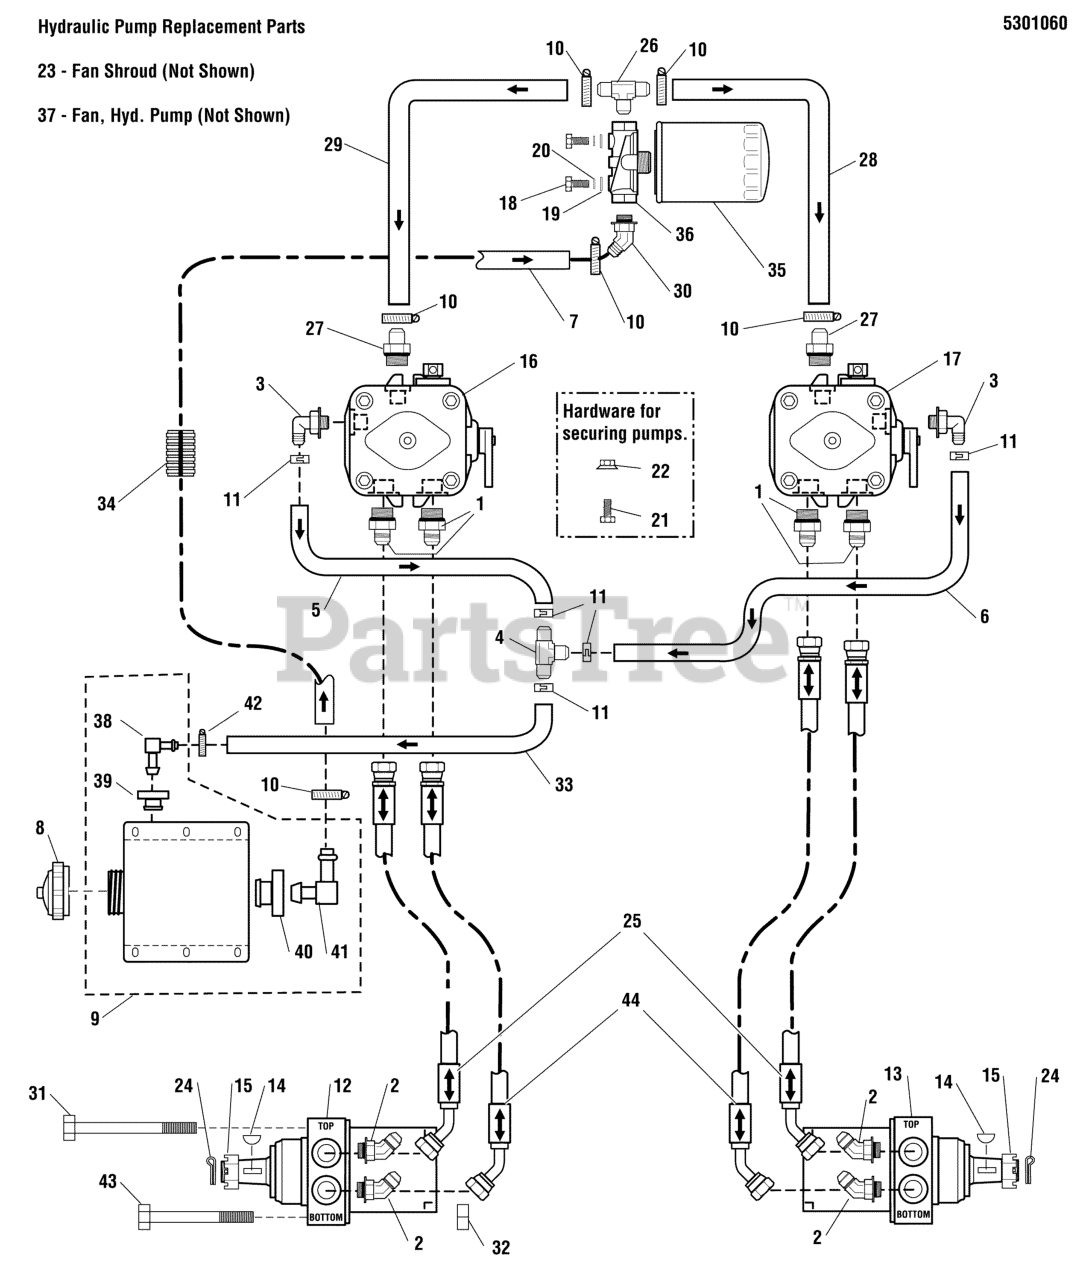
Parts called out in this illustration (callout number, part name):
1	ADAPTER, HYD.
2	FITTING, #8 JIC - #8 O-RING, 45 DEG.
2	FITTING, #8 JIC - #10 O-RING, 45 DEG.
3	ADAPTER, 90 DEG, 9/16-3/8 BARB
4	FITTING, TEE, 1/2 HOSE
5	HOSE, 3/8 PUSH-LOCK X 6.5
6	HOSE, 3/8 PUSH-LOCK X 27
7	HOSE, 5/8, PUSH-LOCK X 21
8	CAP, HYDRAULIC
9	TANK, HYDRAULIC, ASSEMBLY
10	CLAMP, #10 HOSE, STAINLESS
11	CLAMP, HOSE
12	WHEEL MOTOR, LH, 14.5 CI-TF0240LS080AAKZ
13	WHEEL MOTOR, RH, 14.5 CI-TF0240LS081AAKZ
14	KEY, WOODRUFF (SV)
15	NUT, CASTLE 1-20
16	PUMP, HYDRO-GEAR, 12CC - LH
16	PUMP, HYD, 12CC - LH, PK-3HBQ-FV1F-XXXX
17	PUMP, HYDRO-GEAR, 12CC - RH
17	PUMP, HYD, 12CC - RH, PK-3KBQ-FV1F-XXXX
18	BOLT, 1/4-20 X 3/4 GD5 YZ
19	WASHER, 1/4 SAE
20	WASHER, 1/4 LOCK
21	BOLT, 3/8-16 X 1-1/4" GD5 CZ
22	NUT, 3/8-16 HEX SERRATED FLANGE
24	PIN, COTTER, 1/8 X 2
25	HOSE ASSEMBLY 16.75, HP, ST X ST
26	FITTING, BRANCH TEE
27	FITTING, STRAIGHT, HYD #12618
28	HOSE, 5/8, PUSH-LOCK X 11
29	HOSE, 5/8, PUSH-LOCK X 15
30	FITTING, 45 DEG 1/2 NPT MALE - 5/8 HOSE
31	BOLT, 1/2-13 X 2-1/2, NYLON PATCH
32	NUT, 1/2-13 SQUARE
33	HOSE, 3/8 PUSH-LOCK X 15
34	LOOM, CONVOLUTED SPLIT, 1" ID.
35	FILTER, HYDRAULIC, SERVICE PART (PKG)
36	FILTER HEAD
38	FITTING, ELBOW, 3/8" (SV)
39	GROMMET (SV)
40	GROMMET (SV)
41	FITTING, ELBOW, 5/8" (SV)
42	CLAMP # 4 HOSE, STAINLESS
43	BOLT, 1/2-13 X 2-1/4
44	HOSE ASSEMBLY 19.25, HP, ST X ST
